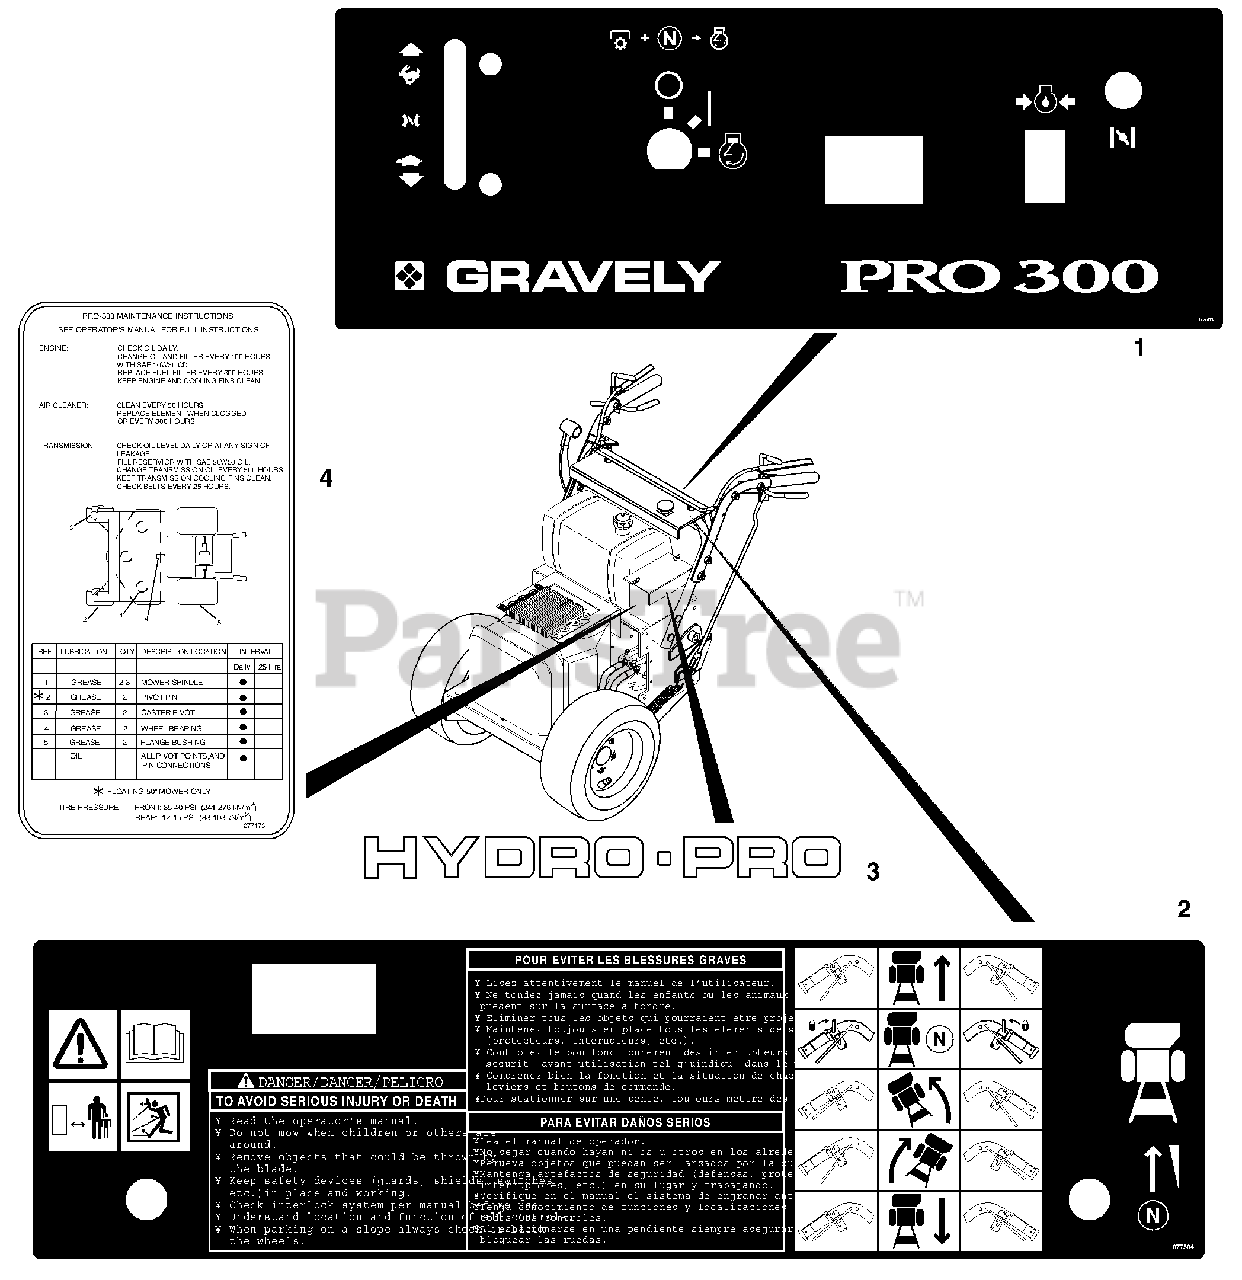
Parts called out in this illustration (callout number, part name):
1	DECAL, PRO-300 PANEL
2	DECAL, PRO-300 PANEL
3	DECAL,HYDRO-PRO
4	DECAL, PRO-300 MAINTENANCE
